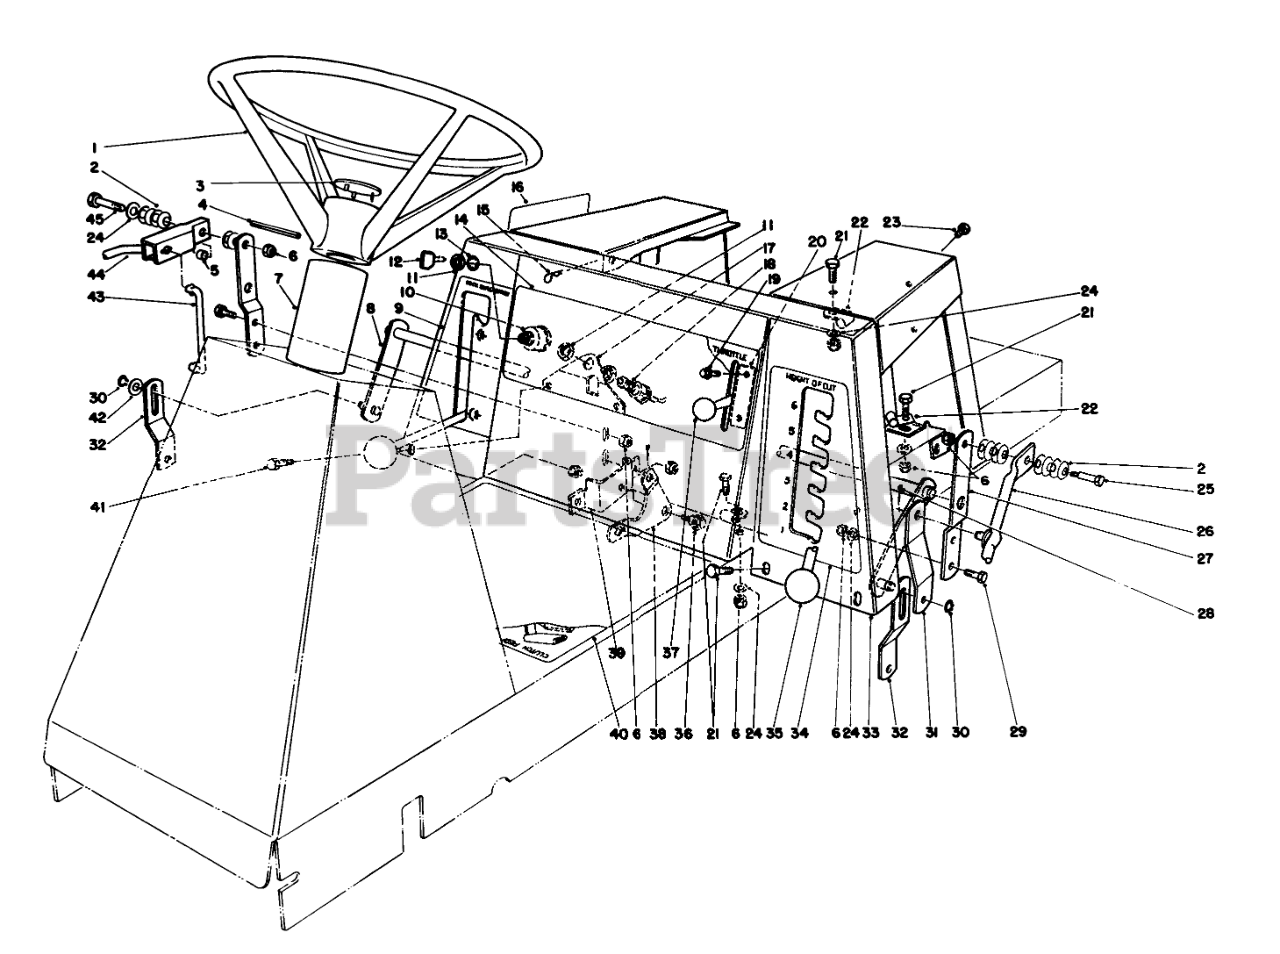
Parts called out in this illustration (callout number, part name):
1	Steering Wheel Assembly (Incl. Ref. #3)
2	WASHER-BELLEVILLE
3	Cap-Steering Wheel
4	PIN-ROLL
5	SPACER
6	NUT-LOCK, NI
7	STRG. SHAFT COVER
8	Arm
9	DECK ENGAGE DECAL
10	Switch-Ignition (Incl. Ref. #11-13)
12	KEY-IGNITION
13	WASHER-TOOTH, INTERNAL
14	IGN & THROTTLE DECAL
15	PIN-COTTER
16	Decal Shift Pattern
17	SWITCH MT BRKT
18	Switch-Deck (Incl. Ref. #11)
19	SCREW-HWHTF
20	Control-Throttle (Incl. Ref. #37)
21	SCREW-HH
22	CLAMP
23	SCREW-HH
24	WASHER-PLAIN
25	BOLT-SHOULDER
26	HOC LEVER WA B
27	Bracket
28	PIN-COTTER
29	SCREW-HH
30	RING-RETAINING
31	HOC ENGAGE BRKT R
32	Link-Deck Suspension
33	Body-Seat
34	HOC DECAL
36	SCREW-SHOULDER
37	Knob
38	DECK ENGAGE BELLCRANK
39	BELLCRANK MTG BRKT
40	INSTRUCTION DECAL
41	SCREW-HH
42	WASHER-FLAT
43	BELLCRANK LINK(PLTD)
44	SHIFT LEVER WA B
45	SCREW-HH
